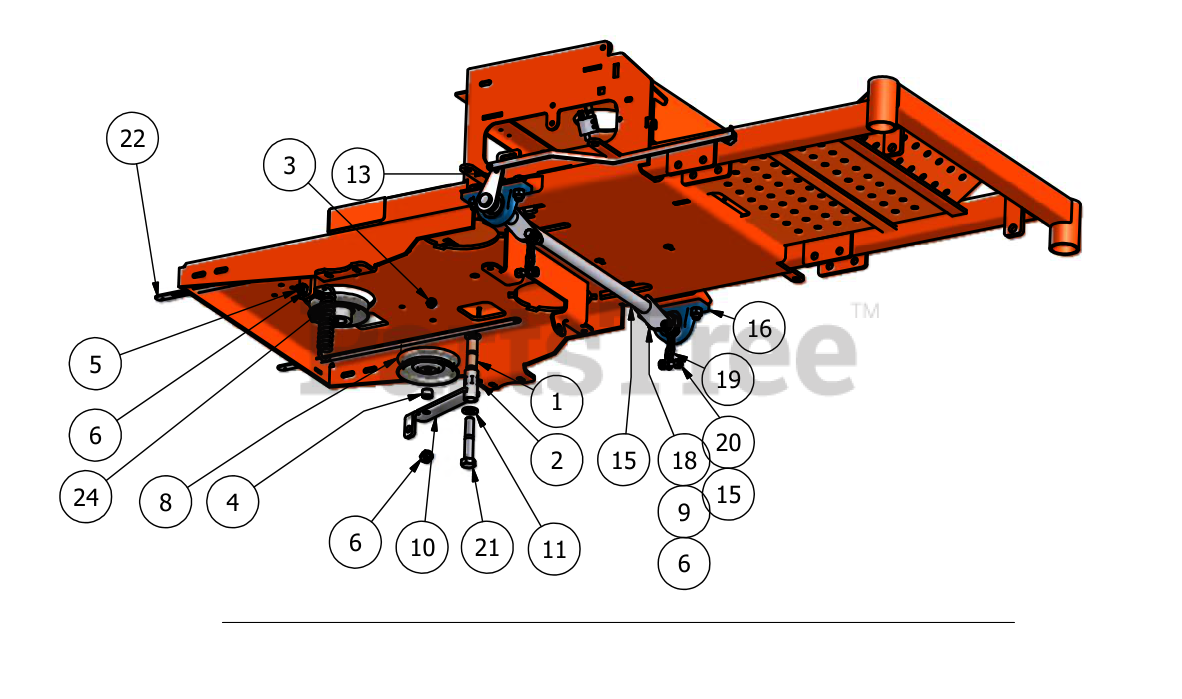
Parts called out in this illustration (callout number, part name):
1	Bronze Bushing
2	Grease Fitting
3	1/2" x 2" Bolt
4	1/2" Spacer
5	Spring Tensioner
6	1/2" Hex Nut
7	Pump Idler Spring
8	4 3/4" Idler Pulley
9	1/2" Lock Washer
10	Pump Idler Bracket
11	5/8" Nylon Washer
12	5/8" Nylock Nut
13	Height Indicator Lever
14	Actuator Bar - Transaxle
15	3/8" Nylock Nut
16	Pillow Block Bearing
17	1/2" x 1 1/2" Hex Bolt
18	Deck Chain
19	3/8" x 1 1/2" Bolt
20	5/8" x 4" Hex Bolt
